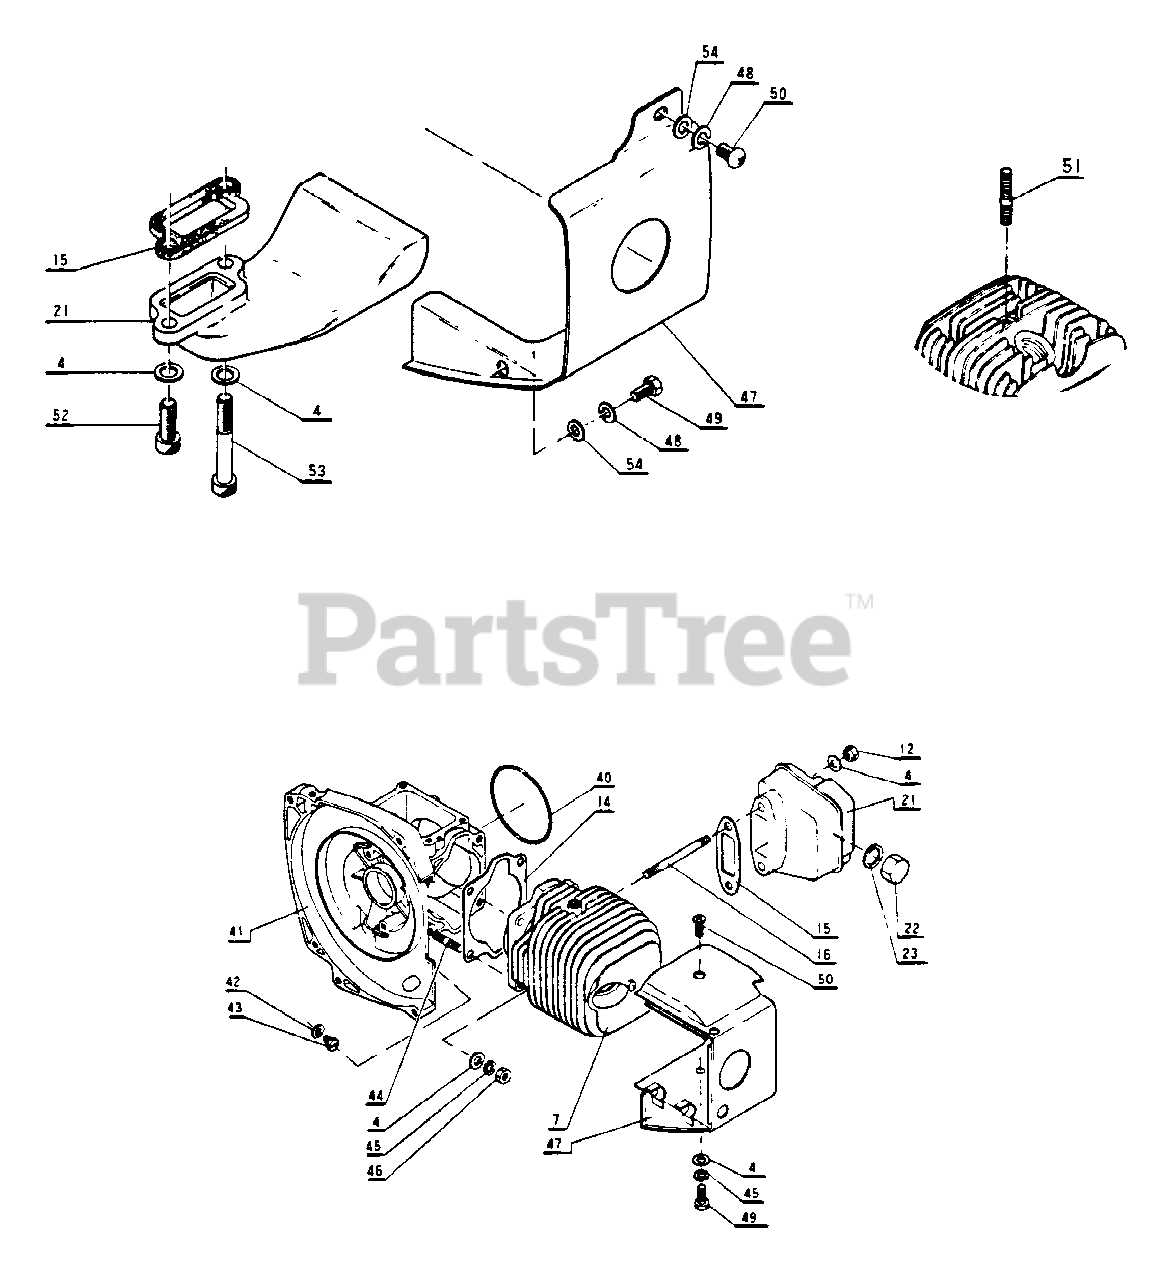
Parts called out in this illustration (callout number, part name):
4	WASHER - 6
7	CYLINDER
12	LOCKNUT - 6
14	GASKET, CYLINDER
15	GASKET, EXHAUST
16	STUD
21	MUFFLER
22	CAP
23	GASKET, CAP
40	O-RING
41	CRANKCASE
42	PACKING
44	STUD
45	LOCKWASHER - 6
46	LOCKNUT - 6
47	SHIELD, CYLINDER
48	WASHER - SPRING
49	SCREW - 6X12
50	SCREW - 6X12
51	STUD
52	BOLT
53	BOLT
54	WASHER
